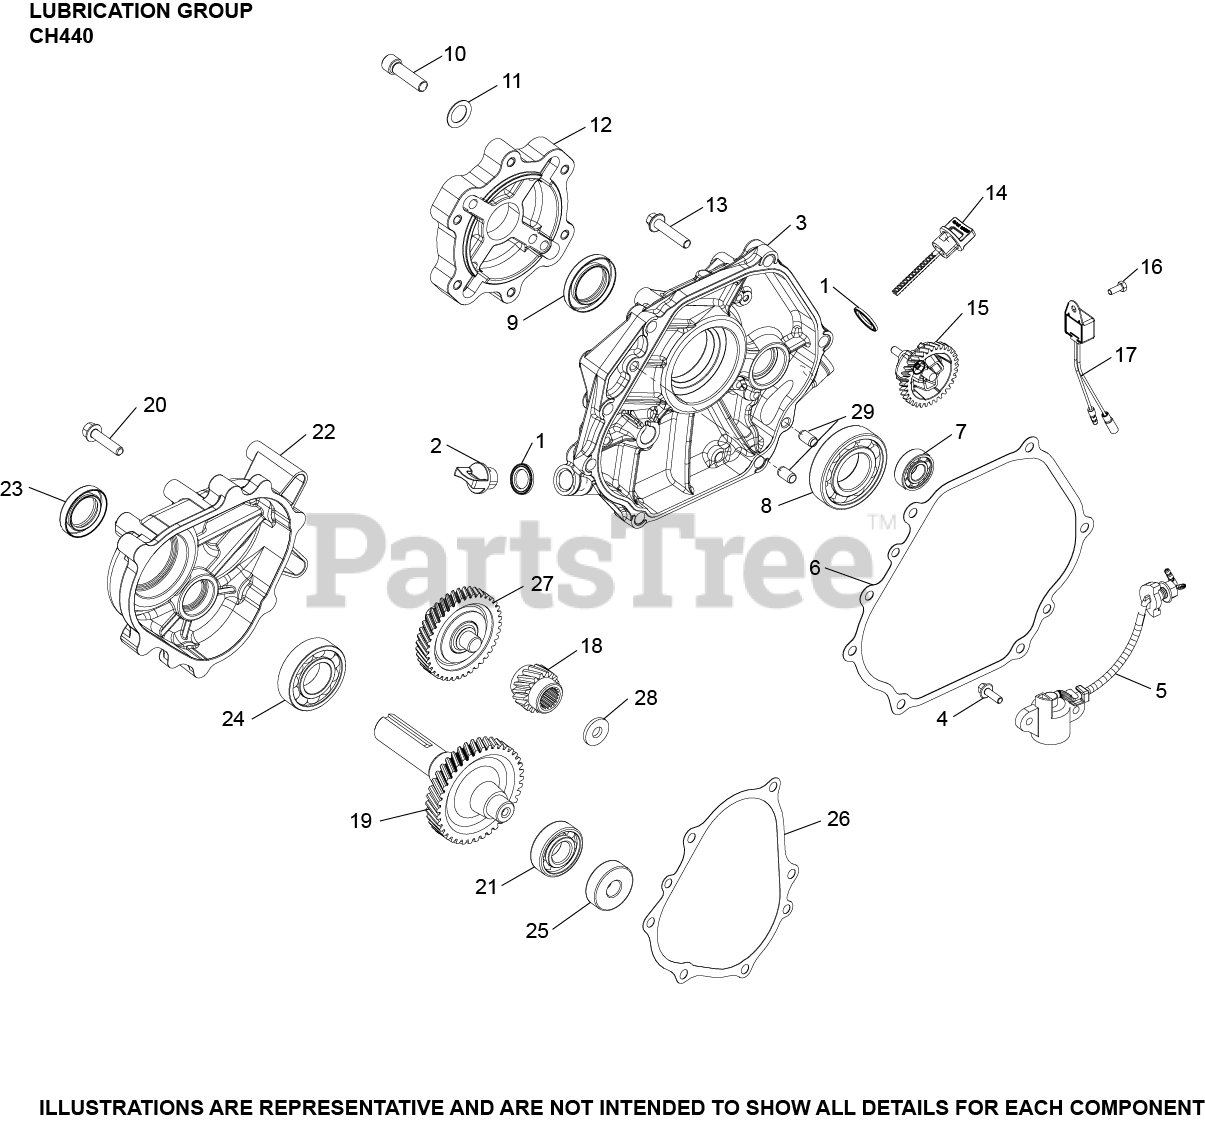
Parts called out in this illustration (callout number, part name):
1	SEAL, OIL
3	KIT, CLOSURE PLATE ASSEMBLY
5	SWITCH, OIL SENSOR ASSEMBLY
6	GASKET, CLOSURE PLATE
13	SCREW, CLOSURE PLATE (CKY)
14	DIPSTICK ASSEMBLY
15	GOVERNOR ASSEMBLY
